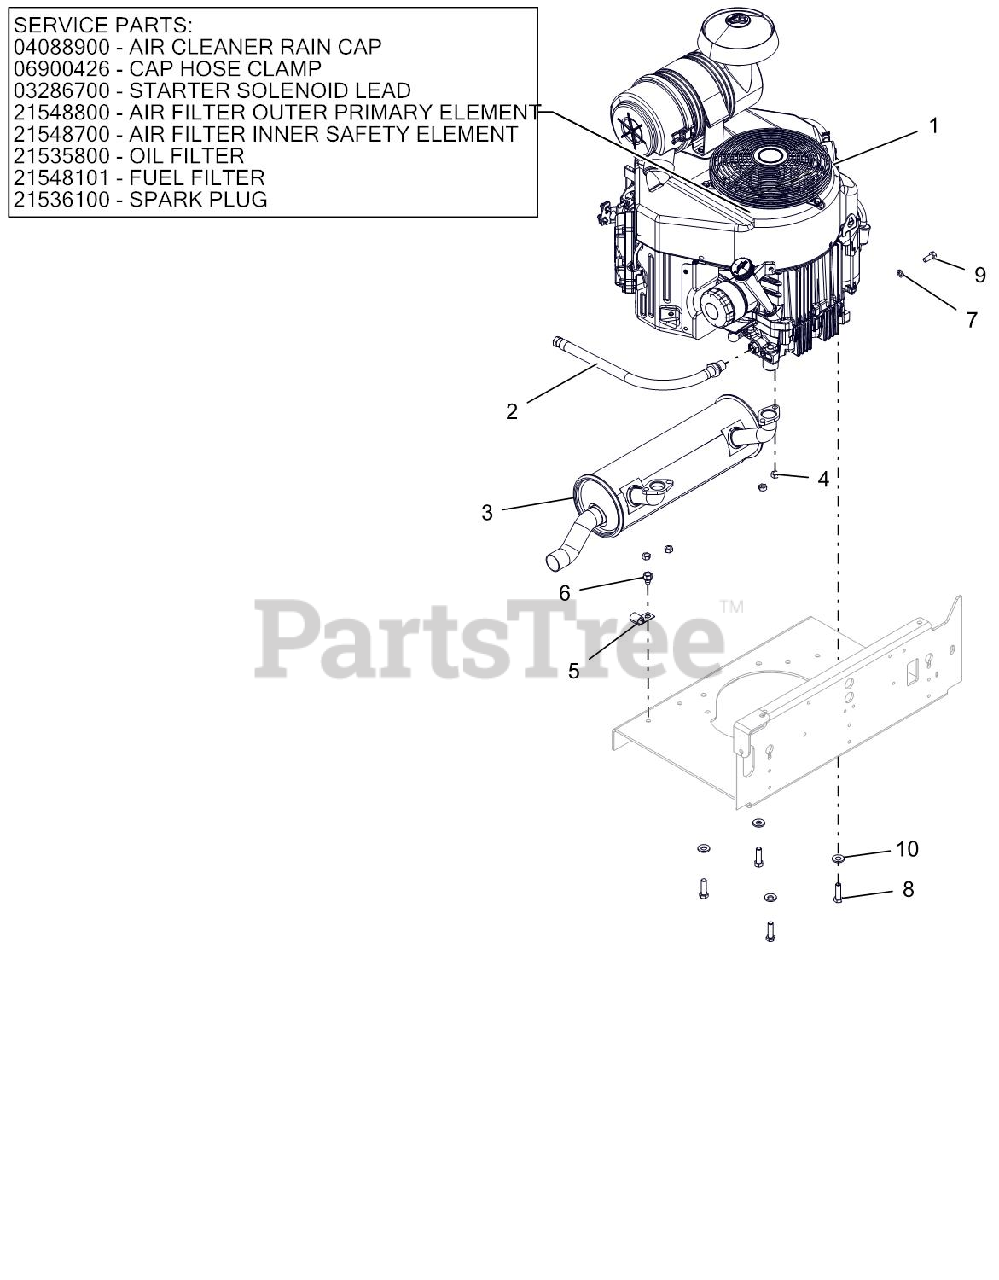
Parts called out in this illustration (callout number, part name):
1	FILTER,OIL - KAW
1	PLUG, SPARK
1	LEAD - STARTER SOLENOID
1	CAP, KAW 11065-7025
1	CLAMP, HOSE #36 SS 1.813-2.75
1	FILTER, OUTER
1	FILTER, INNER - KAW
1	ENGINE, KAWASAKI FX730
1	FUEL FILTER-KAWASAKI FR
2	HOSE, OIL DRAIN
3	MUFFLER, KAW FX691/730
4	NUT-LK-TOP M8-1.25 YWZC
6	@SCR-TAP .38-16X.50 HWH TR YWZ
7	@WSHR-LK .31X.078 REG YWZC
8	BLT-HEX.38-16X1.25 G5YZ NYTORQ
9	@BLT-HEX M8-1.25X20 YWZC
10	WASHER, 3/8" SPRING DISC
